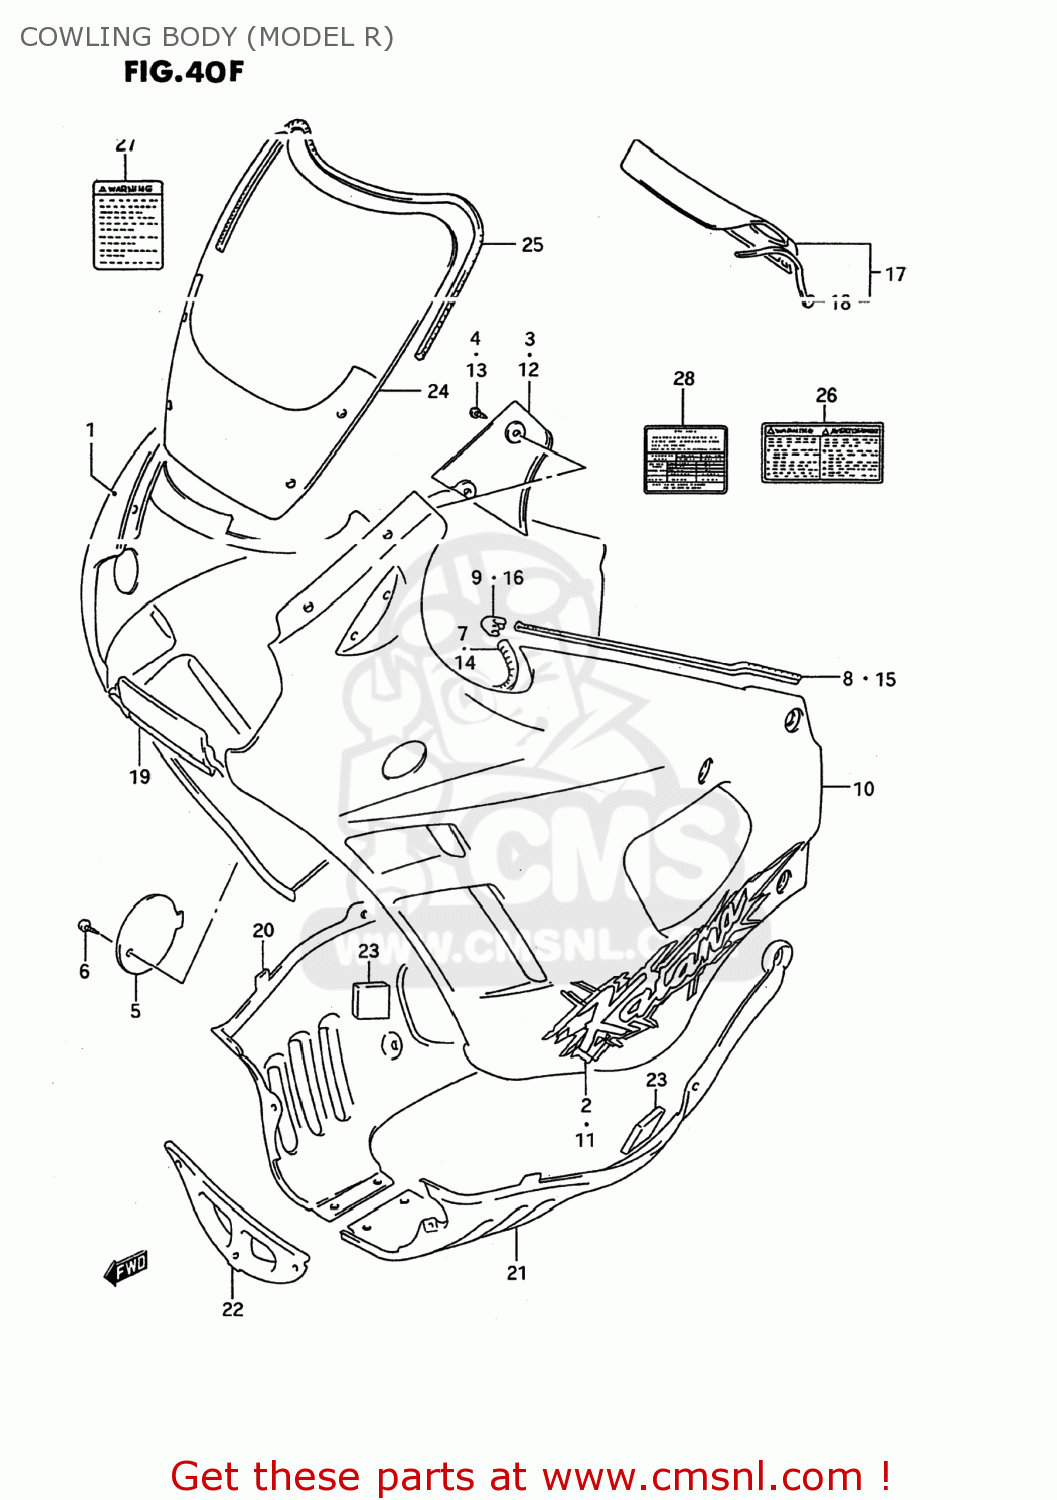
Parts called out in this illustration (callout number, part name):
1	COVER ASSEMBLY,COWLING,RIGHT
2	EMBLEM,BODY COWL SIDE,R
3	COVER,METER SIDE,R
4	SCREW
5	LID,OIL
6	SCREW(6X16)
7	MOLD,COWLING
8	MOLDING
9	JOINT,MOLDING END
10	COVER ASSEMBLY,COWLING,LEFT
11	EMBLEM,BODY COWL SIDE,L
12	COVER,METER SIDE,L(RED)
13	SCREW
14	MOLD,COWLING
15	MOLDING
16	JOINT,MOLDING END
17	COVER,METER
18	MOLDING
19	PANEL,COWLING CTR
20	COVER,COWLING UNDER,R
21	COVER,COWLING,UNDER,LEFT
22	COVER,COWLING UNDER FR
23	CUSHION,UNDER COWLING
24	WINDOW,COWLING
25	MOLDING,WINDSCREEN
26	LABEL,GENERAL WARNING
27	LABEL (WARNING SCREEN)
28	LABEL (TIRE INFORMATION)
